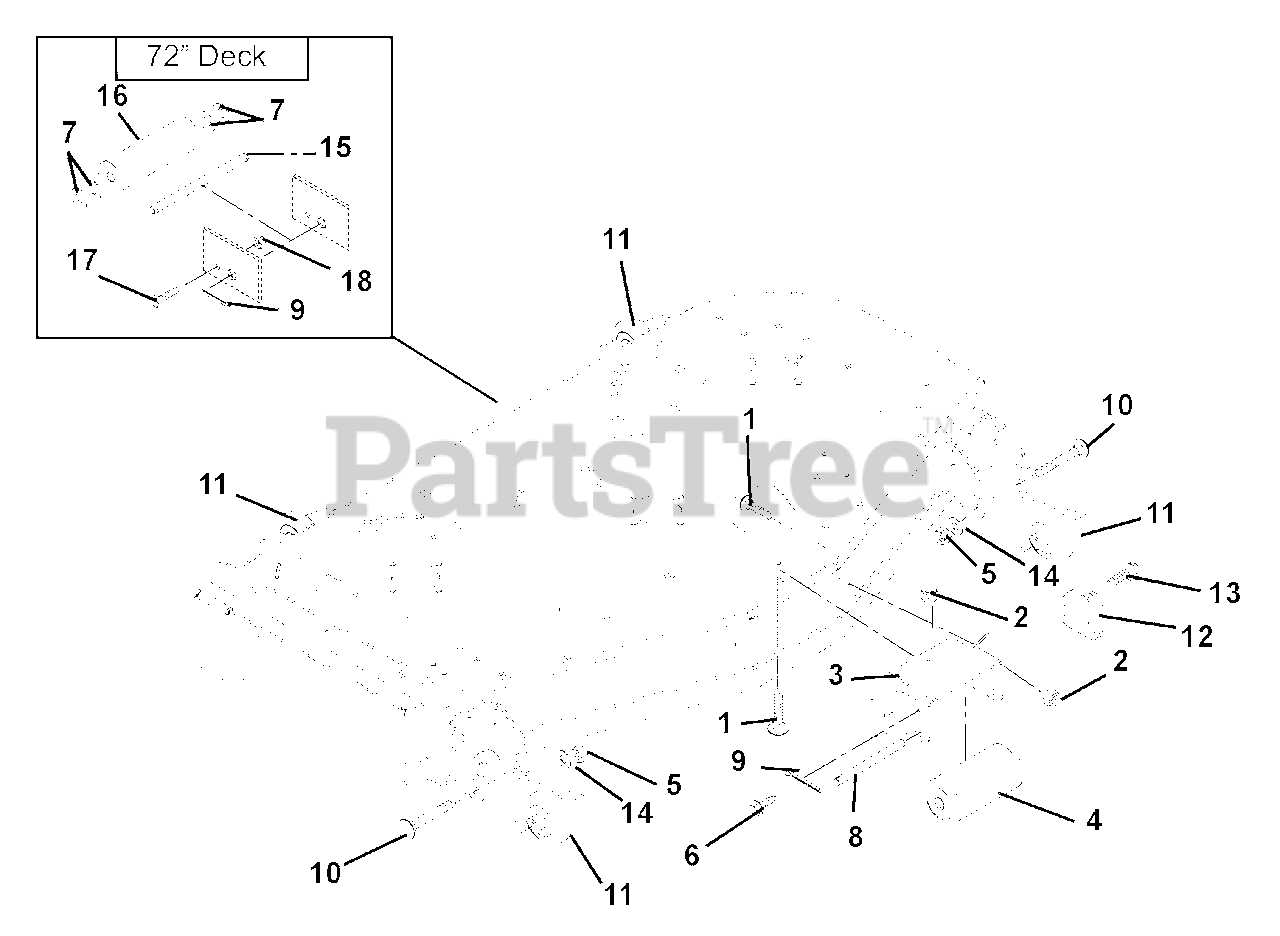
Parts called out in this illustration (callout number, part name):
1	Bolt-Round Head Square Neck .38-16 x 1.00 Grade 5
2	Nut-Locking-Top-Flange .38-16
3	Bracket- Anti-Scalp Roller
5	Nut-Locking-Nylon .50-13
6	Screw-Tapping .25-20 x .75 Hex Washer Head
7	Washer-Flat-Steel .656 x 1.31 x .095
9	Pin-Cotter .25 x 2.00
10	Bolt-Round Head Square Neck .50-13 x 5.00 Grade 2
11	Wheel, 3 x 5
12	Anti-Scalp Washer
13	Screw-Tapping .25-20 x .62 Hex Washer Head
14	Washer-Flat-Steel .531 x 1.06 x .095
15	Shaft, Center Roller
16	Roller, Gage
17	Bolt-Hex .25-20 x .75 Grade 5
18	Nut-Locking-Center .25-20
